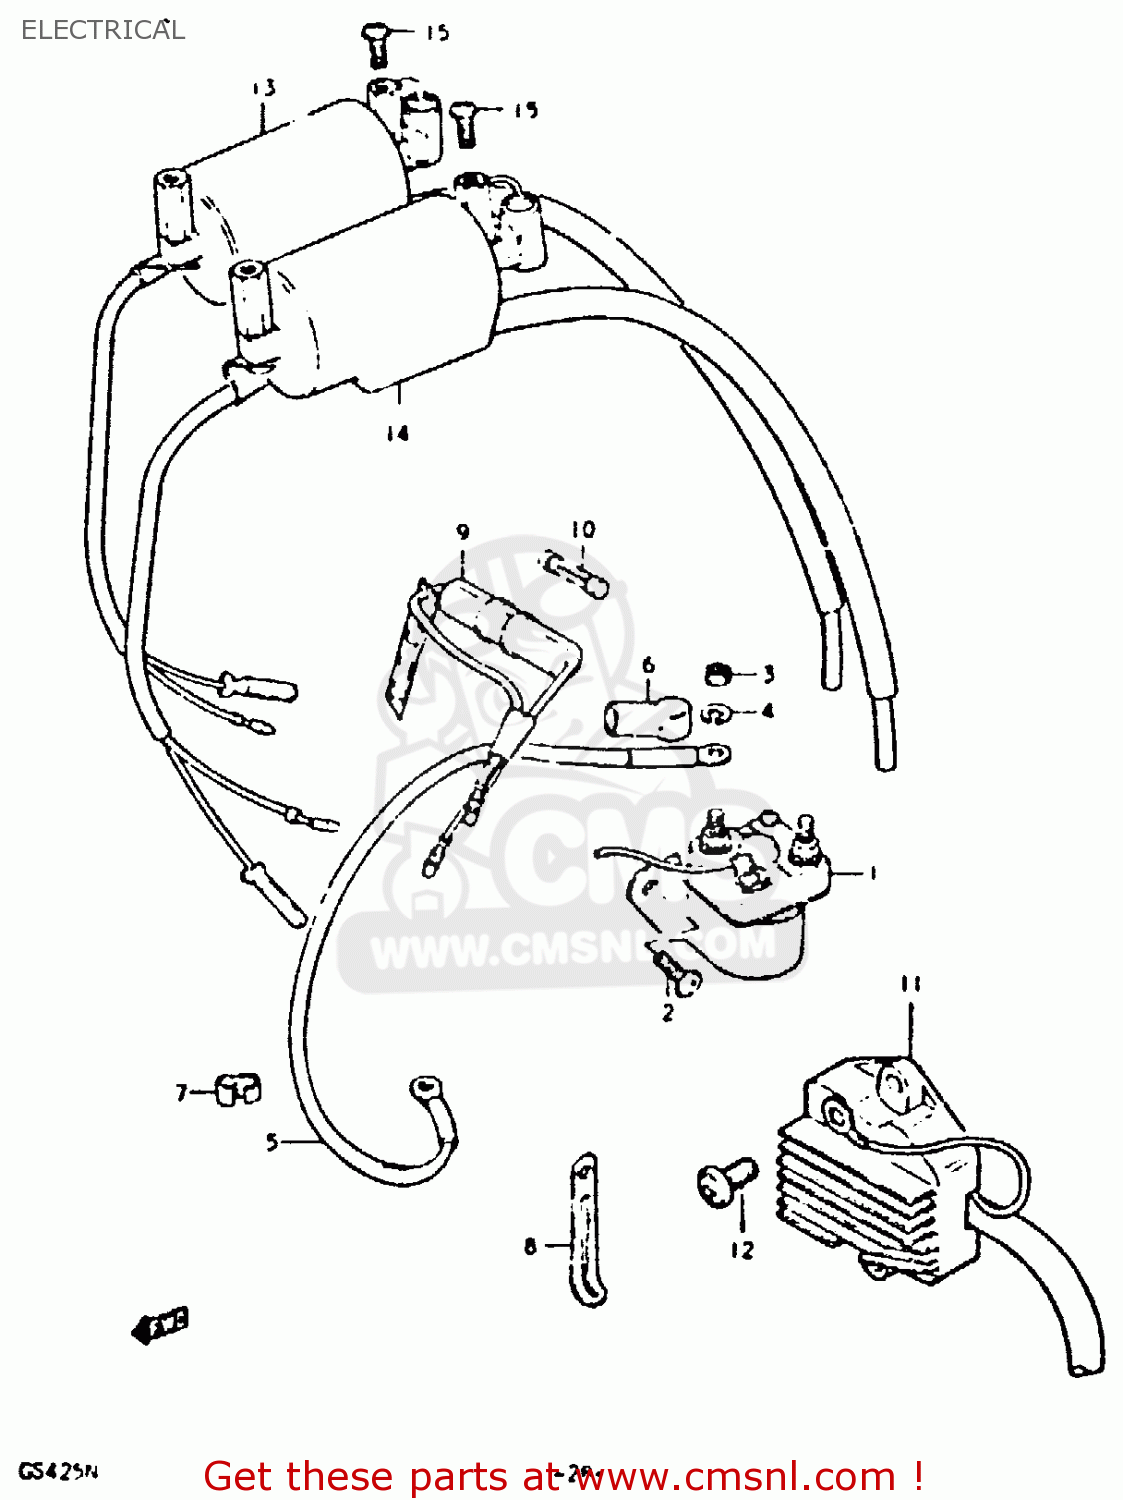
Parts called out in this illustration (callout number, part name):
1	RELAY ASSY,STARTING MOTOR
2	SCREW
3	NUT 6MM
4	LOCK WASHER
5	WIRE,STARTER MOTOR LEAD
6	CAP,STARTER RELAY
7	CLIP
8	CLAMP L:35
9	BOX ASSEMBLY,FUSE
10	FUSE(15A)
11	RECTIFIER ASSEMBLY
12	SCREW
13	COIL ASSEMBLY,IGNITION
14	COIL ASSEMBLY,IGNITION
15	SCREW
